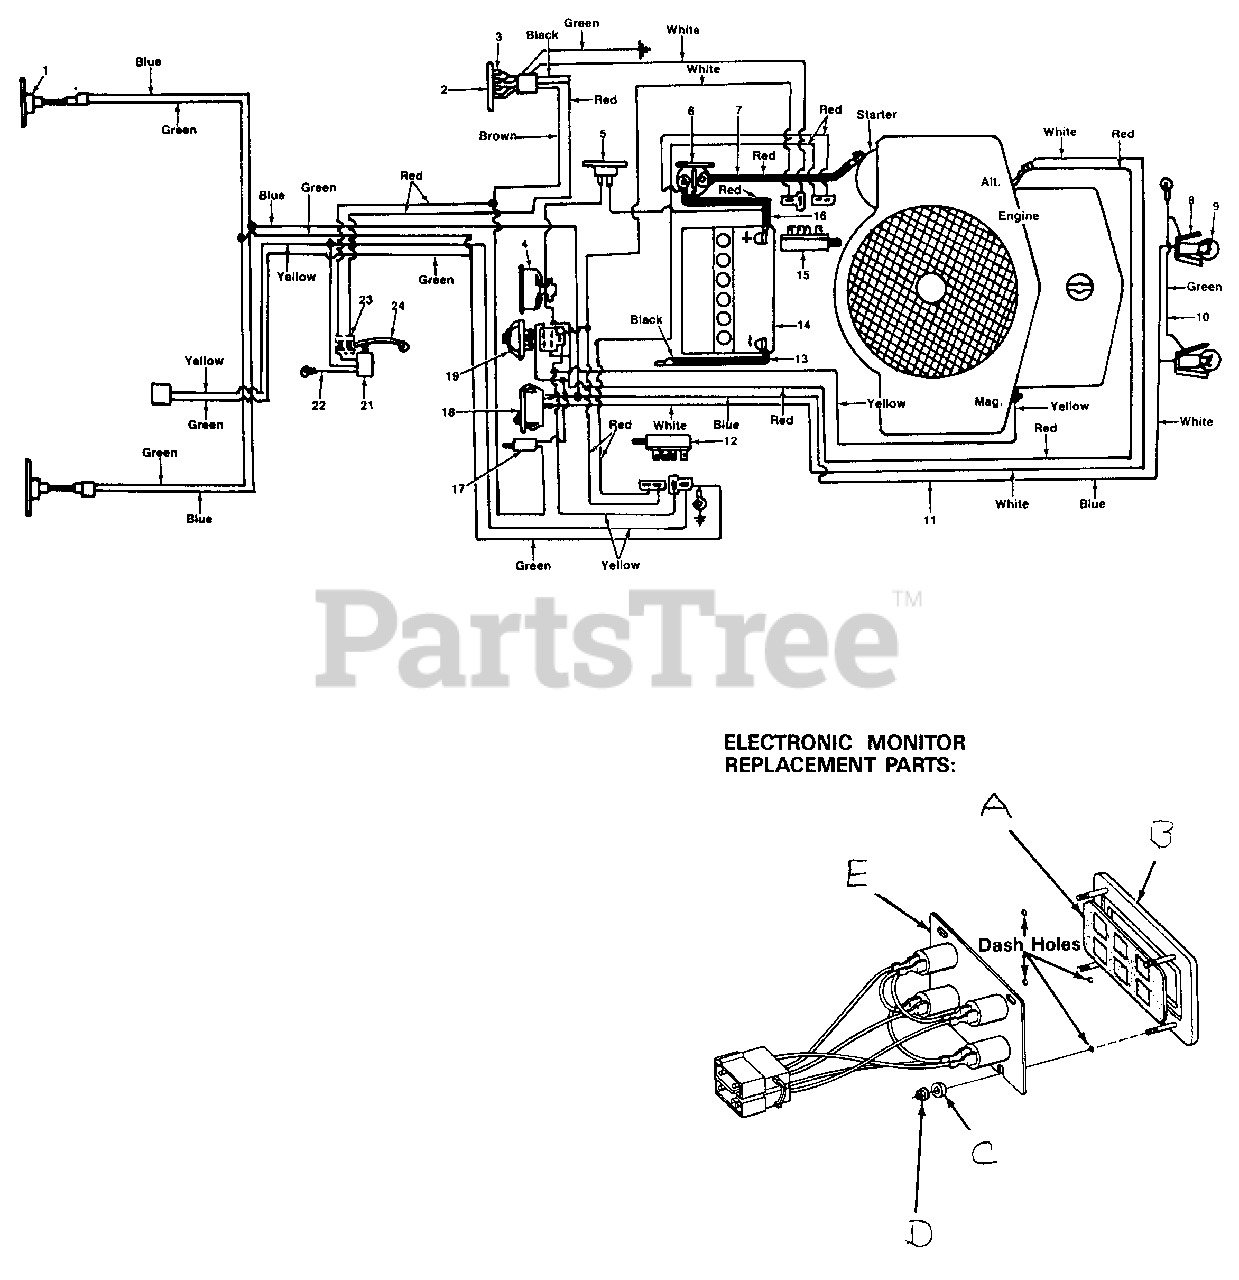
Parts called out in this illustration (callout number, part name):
1	Taillight
2	Indicator Light Ass'y.
4	Ammeter
5	Circuit Breaker
6	Solenoid
7	Wire
8	Socket
9	Bulb
10	Ground Wire
11	Wire Harness
12	Safety Switch
13	6 Ga. Black Wire 7.5" Lg.
14	12V Battery
15	Safety Switch
17	Safety Switch N.O. Black
18	Headlight Switch
19	Ignition Switch
21	Safety Switch
22	Elec. Wire
23	Switch Lead Adapter
24	Spring Lever
